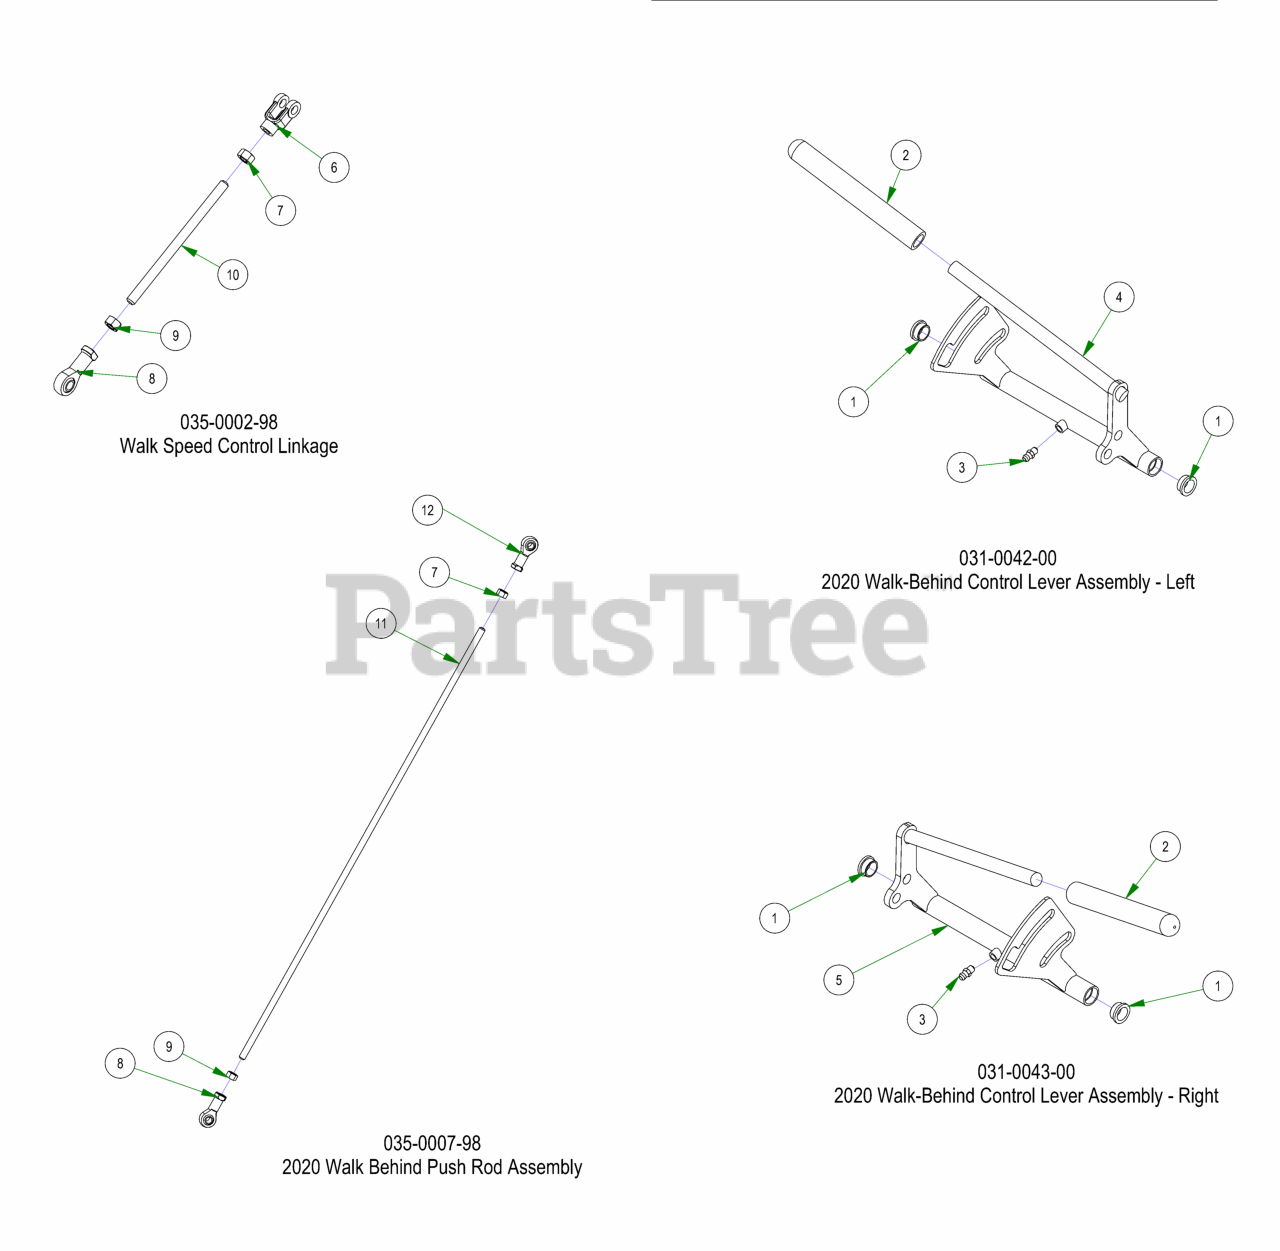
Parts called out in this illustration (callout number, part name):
1	2019 Drive Arm Bushing
2	2019 Stand On Control Grip
3	1/4 DRIVE-TYPE STRAIGHT GREASE FITTING ZINC YELLOW)
4	2020 Walk-Behind Control Lever Weldment - Left
5	2020 Walk-Behind Control Lever Weldment - Right
6	Yoke Left Hand Thread
7	3/8" Left-Handed Fine Threaded Jam Nut
8	Spherical Rod End - Outlaw
9	3/8-24 Hex Nut Zinc
10	Walk Speed Control Rod
11	2020 Walk Behind Push Rod (Rod Only)
12	Swivel Heim left handed thread
